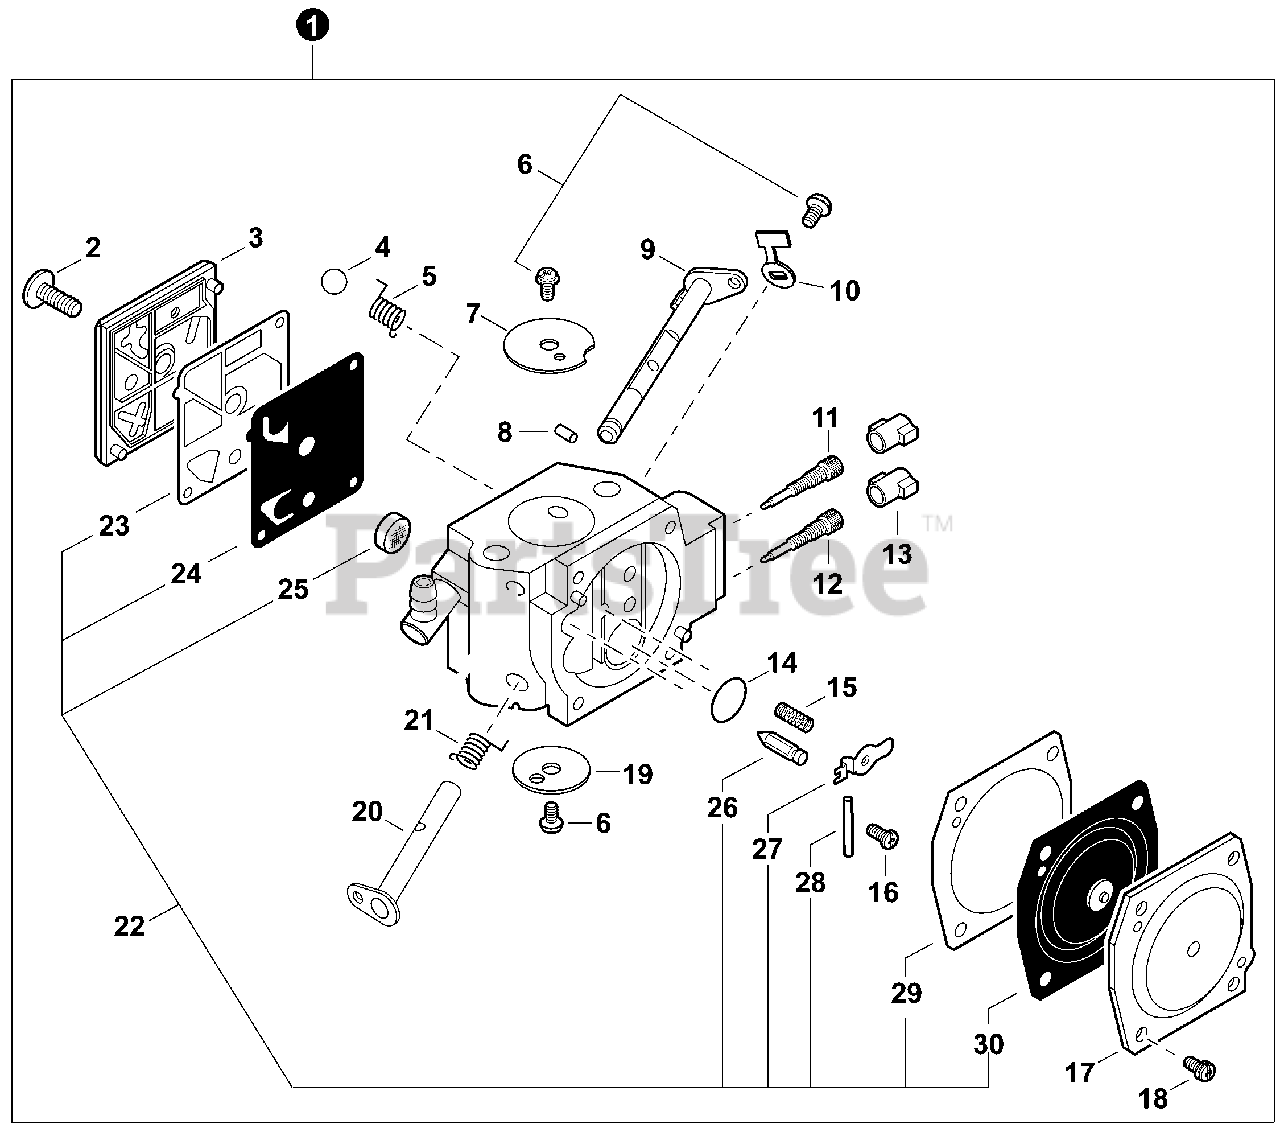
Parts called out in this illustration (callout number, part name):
1	CARBURETOR - HDA-153B
3	COVER, FUEL PUMP
4	BALL, CHOKE FRICTION
7	VALVE, CHOKE
8	PLUG, FRICTION
9	SHAFT, CHOKE
10	STOP, THROTTLE
11	NEEDLE, HIGH SPEED
12	NEEDLE, MIXTURE
13	CAP, LIMITER
14	PLUG, WELCH
16	SCREW, METERING LEVER PIN
17	COVER, METERING DIAPHRAGM
19	VALVE, THROTTLE
20	SHAFT, THROTTLE
21	SPRING, THROTTLE RETURN
22	REPAIR KIT
23	GASKET, FUEL PUMP
24	DIAPHRAGM, FUEL PUMP
25	SCREEN, FUEL INLET
26	VALVE, INLET NEEDLE
27	LEVER, METERING
28	PIN, METERING LEVER
29	GASKET, METERING DIAPHRAGM
30	DIAPHRAGM, METERING
